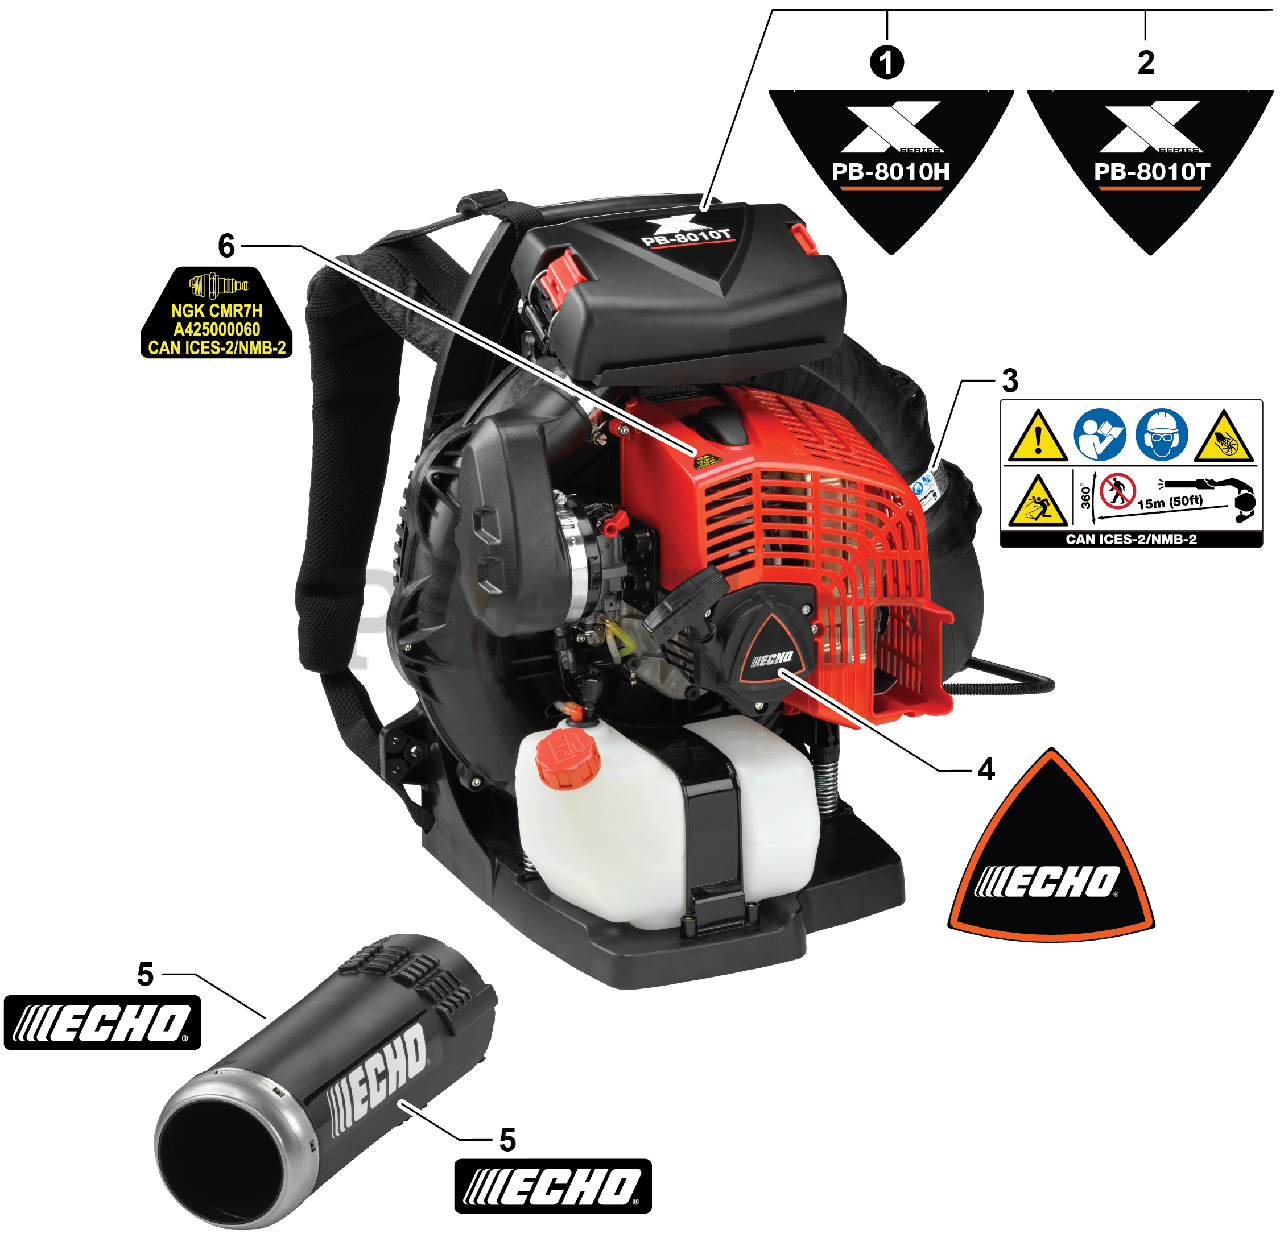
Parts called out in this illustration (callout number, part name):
1	LABEL - PB-8010H
2	LABEL - PB-8010T
3	LABEL - CAUTION
4	LABEL - RECOIL STARTER
5	LABEL - ECHO
6	LABEL - SPARK PLUG - CMR7H
